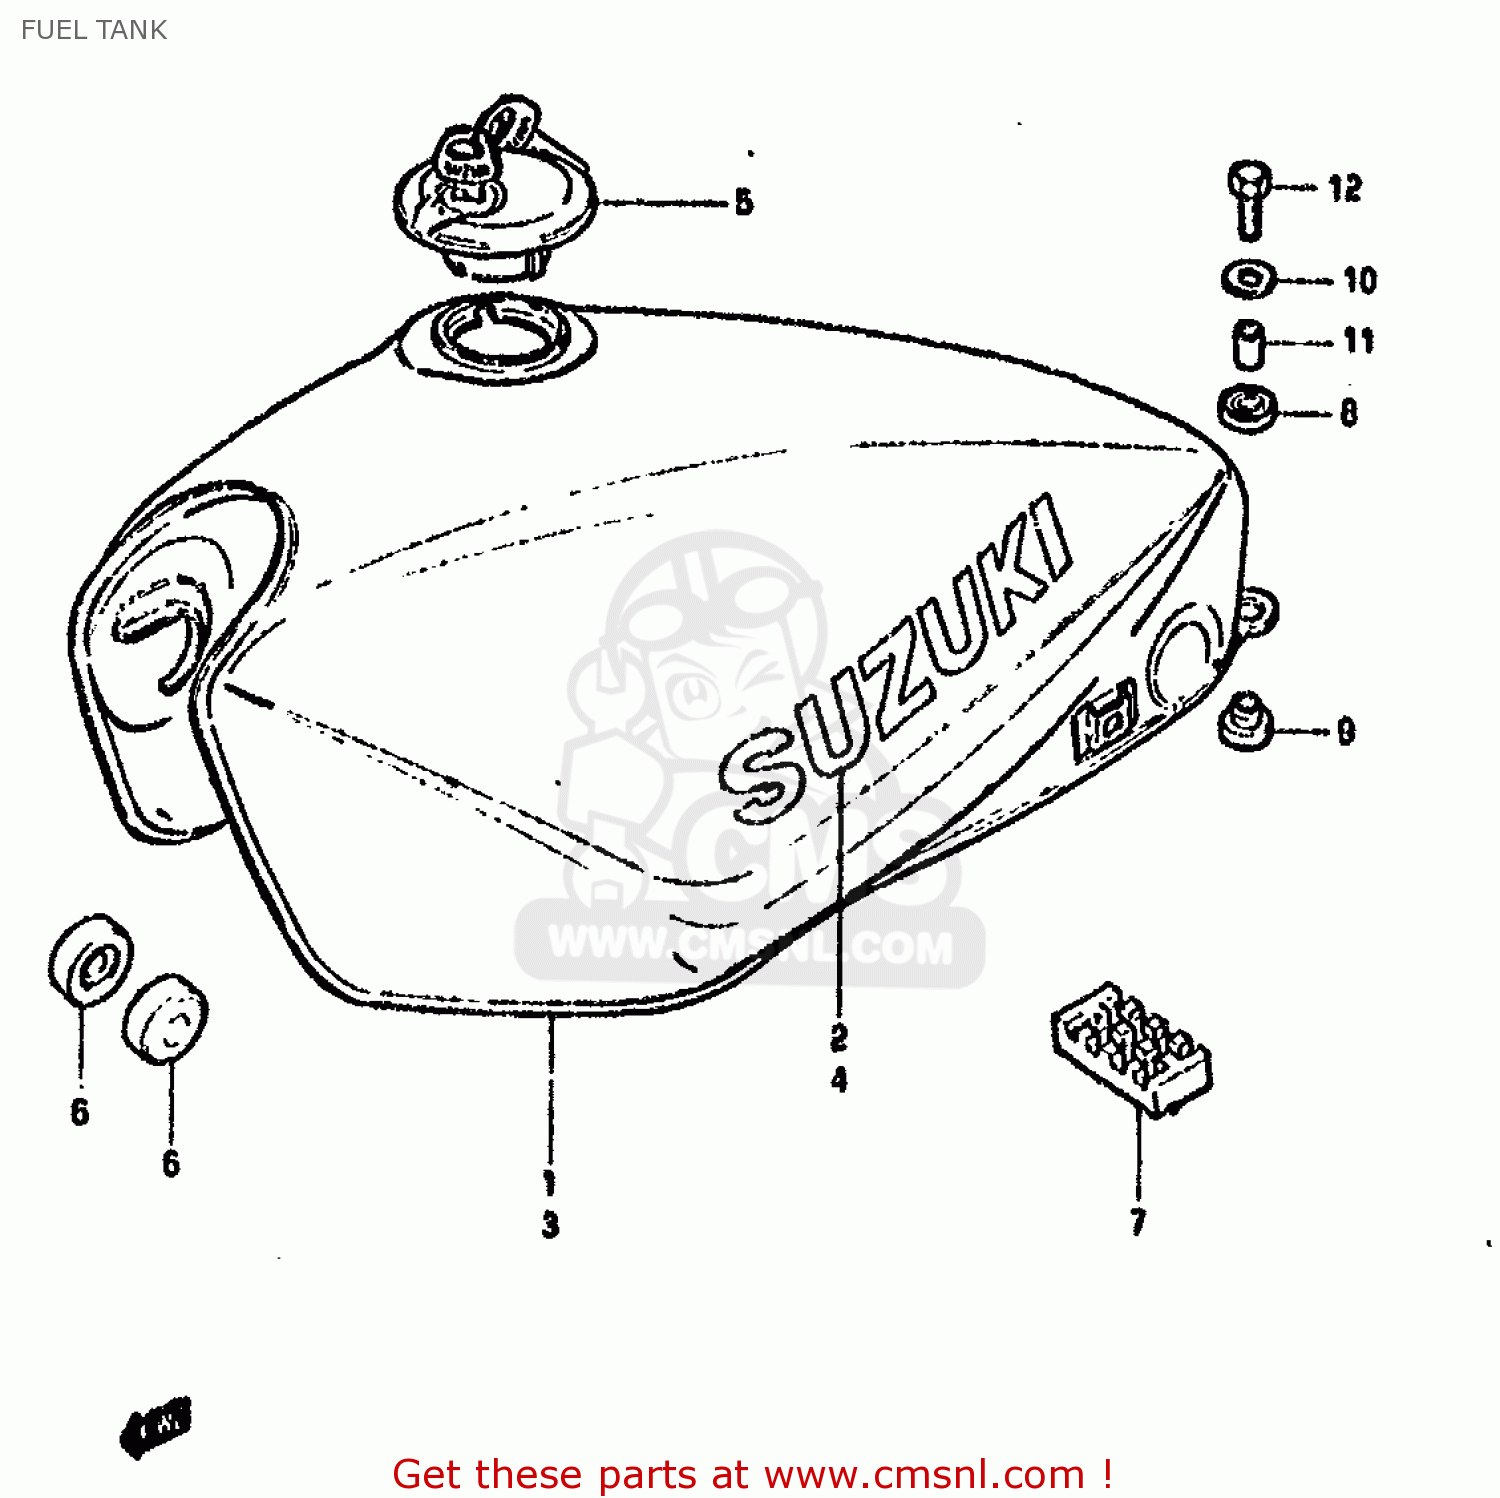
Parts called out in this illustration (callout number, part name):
1	TANK, FUEL (SILVER)
2	EMBLEM(ORANGE)
3	TANK, FUEL (RED)
4	EMBLEM(WHITE)
5	CAP SET,FUEL TANK
6	CUSHION
7	CUSHION,FUEL TANK CTR
8	CUSHION
9	CUSHION
10	WASHER (6.5X24X1.6)
11	SPACER
12	BOLT
